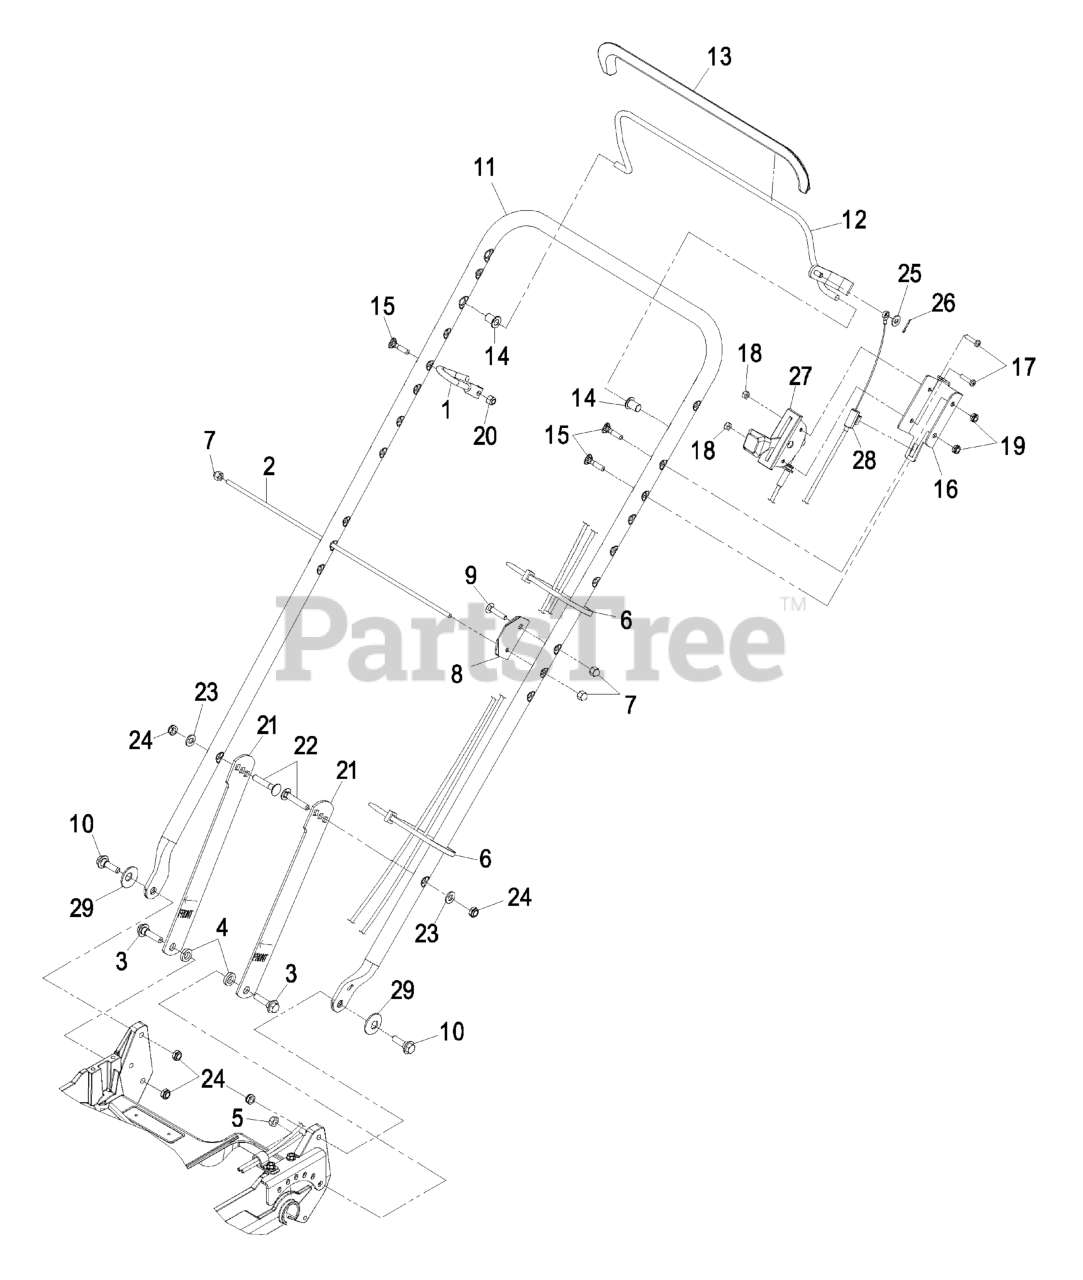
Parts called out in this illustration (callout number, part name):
1	GUIDE-ROPE
2	ROD,BAG SUPPORT
3	SCREW-SHOULDER
4	SPACER
5	NUT-LOCK, NI
6	TIE-CABLE
7	NUT-CAP
9	SCREW-CARR
10	SCREW-SHOULDER
11	WLD,BAIL DEADMAN (PLATED)
13	PAD,DEADMAN
15	SCREW-HANDLE
16	BRACKET,THROTTLE
17	SCREW-PPH
18	NUT-LOCK, NI
19	NUT-LOCK, NI
20	NUT-LOCK, NI
22	BOLT-CARR
23	WASHER-PLAIN
24	NUT-LOCK, NI
25	WASHER-FLAT
26	PIN-COTTER
27	CABLE,THROTTLE KAWASAKI
28	CABLE,BRAKE KAWASAKI
29	WASHER-SPRING
